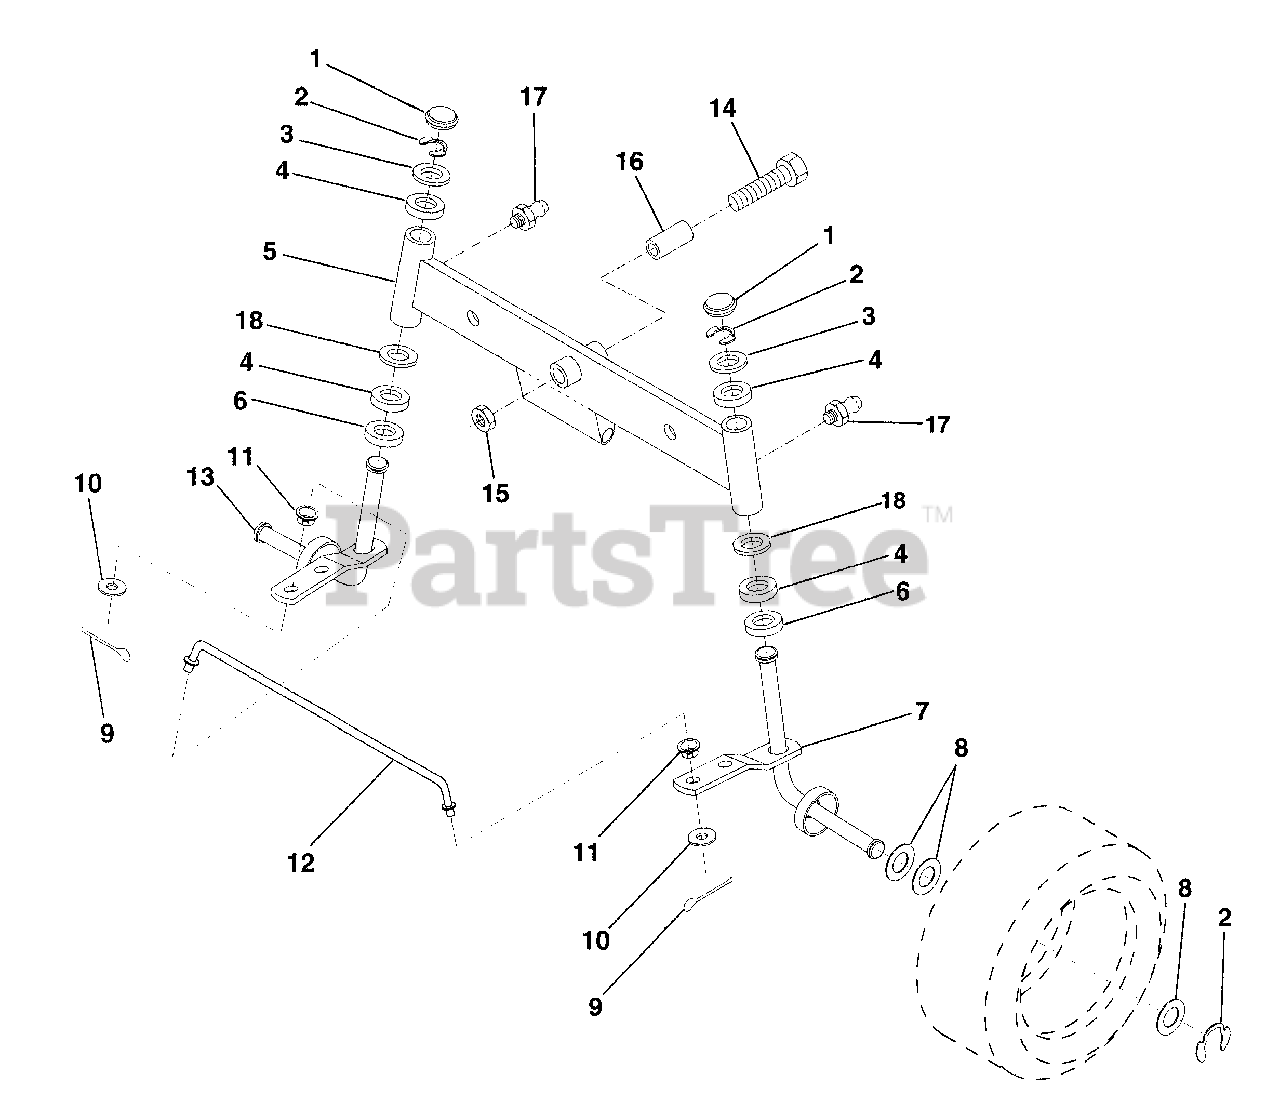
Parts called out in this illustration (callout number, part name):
1	Cap, Spindle
2	Ring, Clip
3	Washer 25/32 x 1-5/8 x 16 Gauge
4	Bearing
5	Axle, Front
6	Bearing, Thrust
7	Spindle Assembly, R.H.
8	Washer 25/32 x 1-1/4 x 16 Gauge
9	Pin, Cotter 1/8 x 3/4
10	Washer 13/32 x 13/16 x 16 Gauge
12	Rod, Tie
13	Spindle Assembly, L.H.
14	Bolt, Hex Head 5/8-11 x 3-1/2
15	Locknut, Flange 5/8-11
16	Spacer, Bearing, Front Axle
17	Grease Fitting
18	Washer 27/32 x 1-1/4 x 16 Gauge
